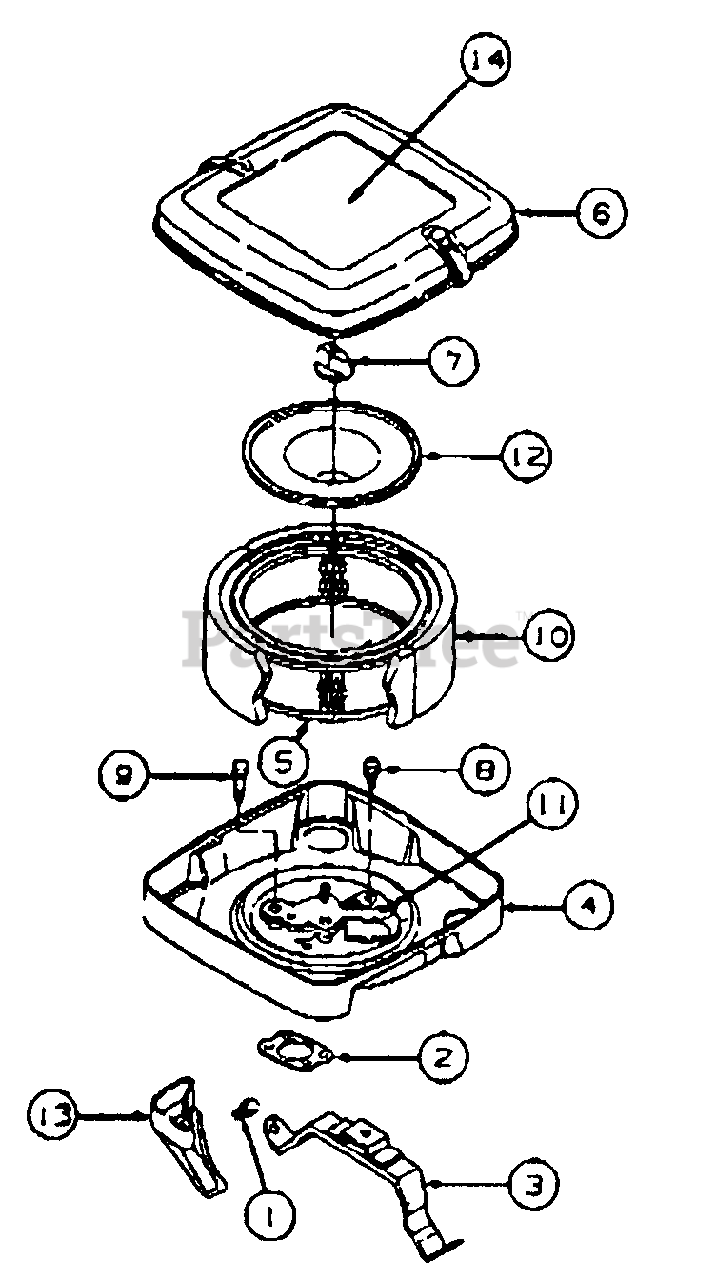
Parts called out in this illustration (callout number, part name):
1	Screw, Sems
2	Gasket, Air Cleaner
3	Bracket, Air Cleaner
4	Base, Air Cleaner
5	Cartridge, Air Cleaner
6	Cover, Air Cleaner
7	Knob, Air Cleaner
8	Screw, Sems
9	Screw, Sems
10	Element, Foam
11	Shield Assembly
12	Plate, Air Cleaner
13	Tube, Air Inlet
14	Label, V-Twin Engine
